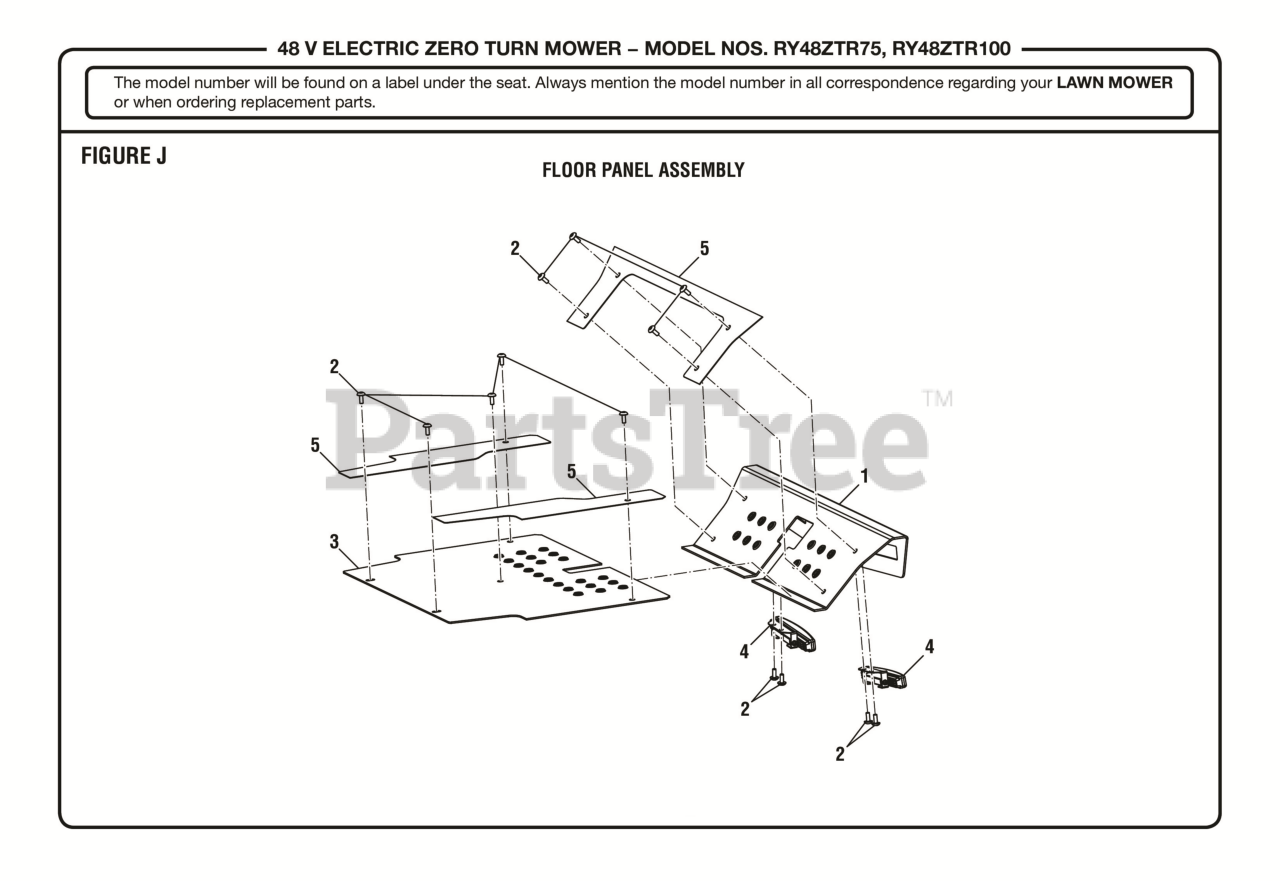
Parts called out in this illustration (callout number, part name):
1	Foot Rest Plate
2	Screw (M6 x 10 mm, Soc. Button Hd.)
3	Floor Plate
4	Light Assembly
5	Anti Slip Decal Package
